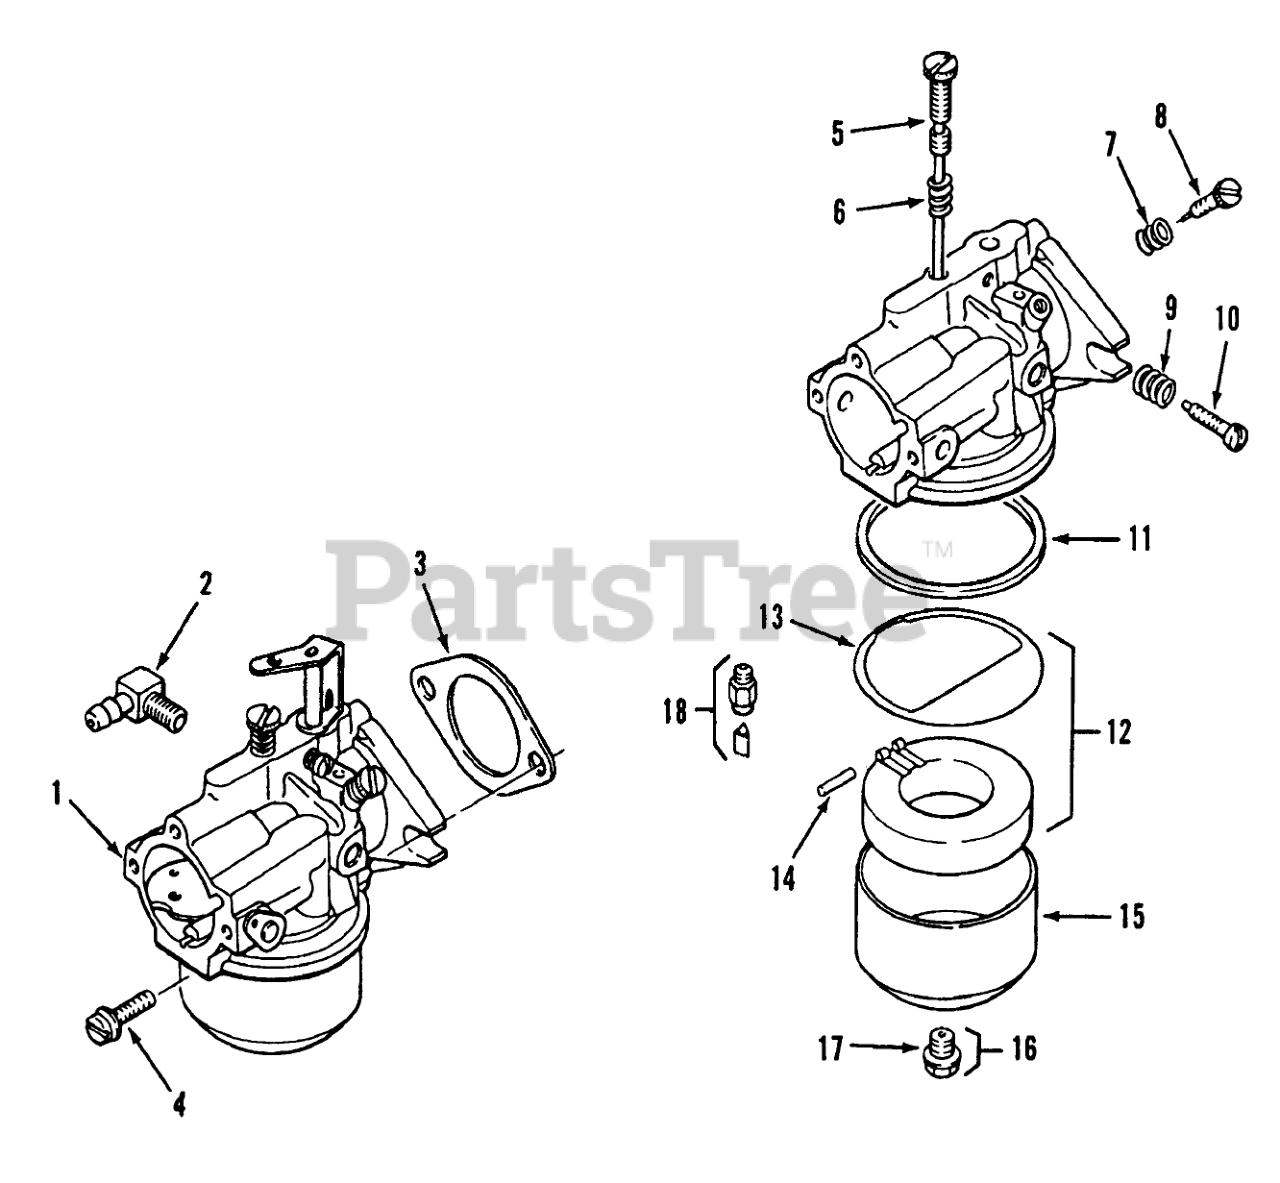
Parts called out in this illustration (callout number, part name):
1	Carburetor Assembly (Includes 5 thru 8) 310, 312
1	Carburetor Assembly (Includes 5 thru 8) 414
2	Connector 90
3	Gasket
4	Screw
5	Main Fuel Adj. Needle 310, 312
5	Main Fuel Sdj. Needle 414
6	Main Fuel Spring
7	Idle Fuel Spring
8	Idle Fuel Adj. Needle 310, 312
8	Idle Fuel Adj. Needle 414
9	Idle Speed Spring
10	Screw
11	Bowl Gasket
12	Float Kit (Includes Item 13)
13	Bowl Baffle Gasket
14	Float Hinge Pin
15	Fuel Bowl
16	Fuel Bowl Retainer Screw (Includes Item 17)
17	Bowl Retainer Screw Gasket
